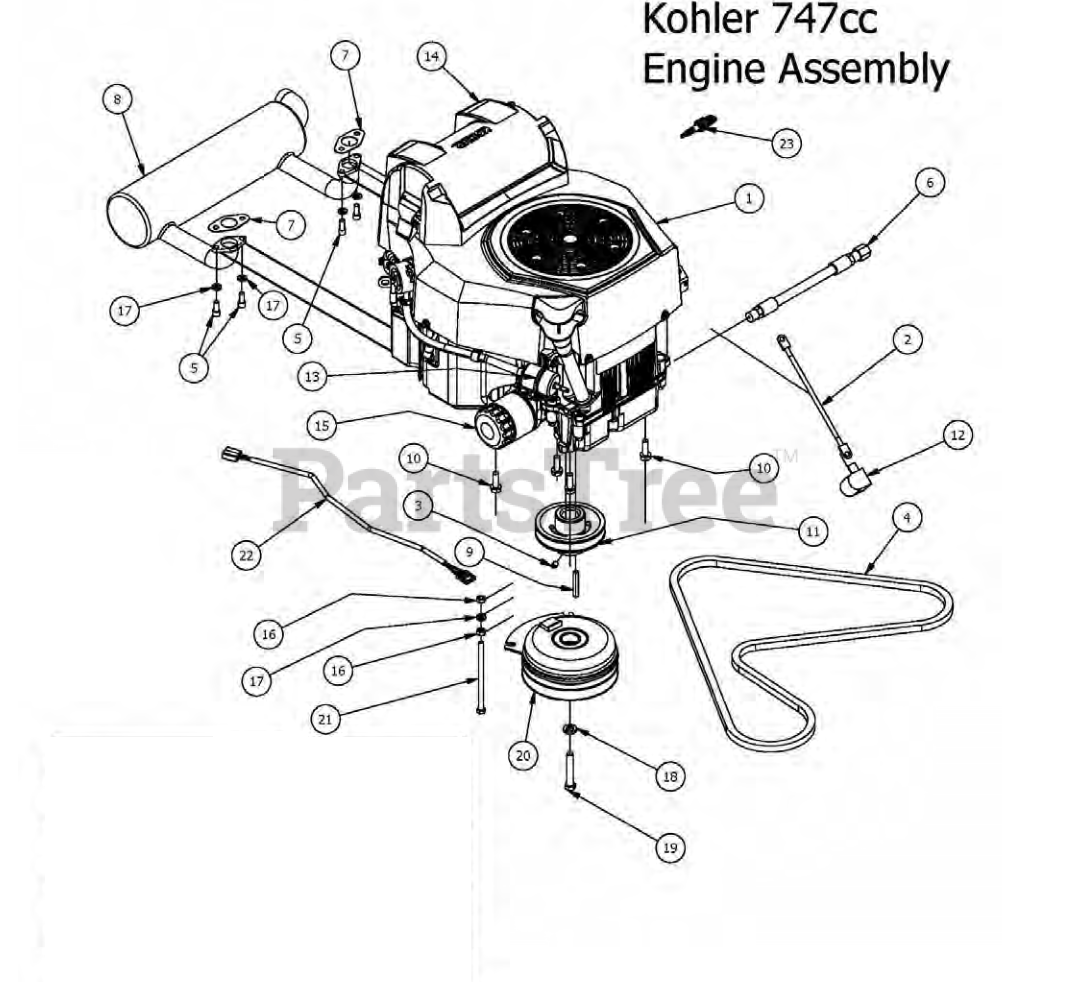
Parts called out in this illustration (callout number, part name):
1	Kohler 747cc Engine
2	Ground Cable
3	5/16 Set Screw
4	75.8 Pump Belt
5	5/16-18 x 3/4 Socket C/S
6	Oil drain Valve
7	Exhaust Gasket
8	Kohler Exhaust
9	1/4 x 2 Square key Stock
10	3/8 x 1 1/8 bolt
11	4 3/4 Motor Pulley
12	Black Boot For Ground Cable
13	Universal Inline Fuel Filter
14	725 Kohler air filter
15	725 & 747 Kohler Oil Filter
17	5/16" Lock Washer
18	7/16" Lock Washer
19	7/16" x 2 1/2" Hex Bolt
20	Clutch Assembly
21	5/16-18 x 5-1/2 GR 5 Hex Bolt
22	Clutch Pigtail
23	Spark Plug
